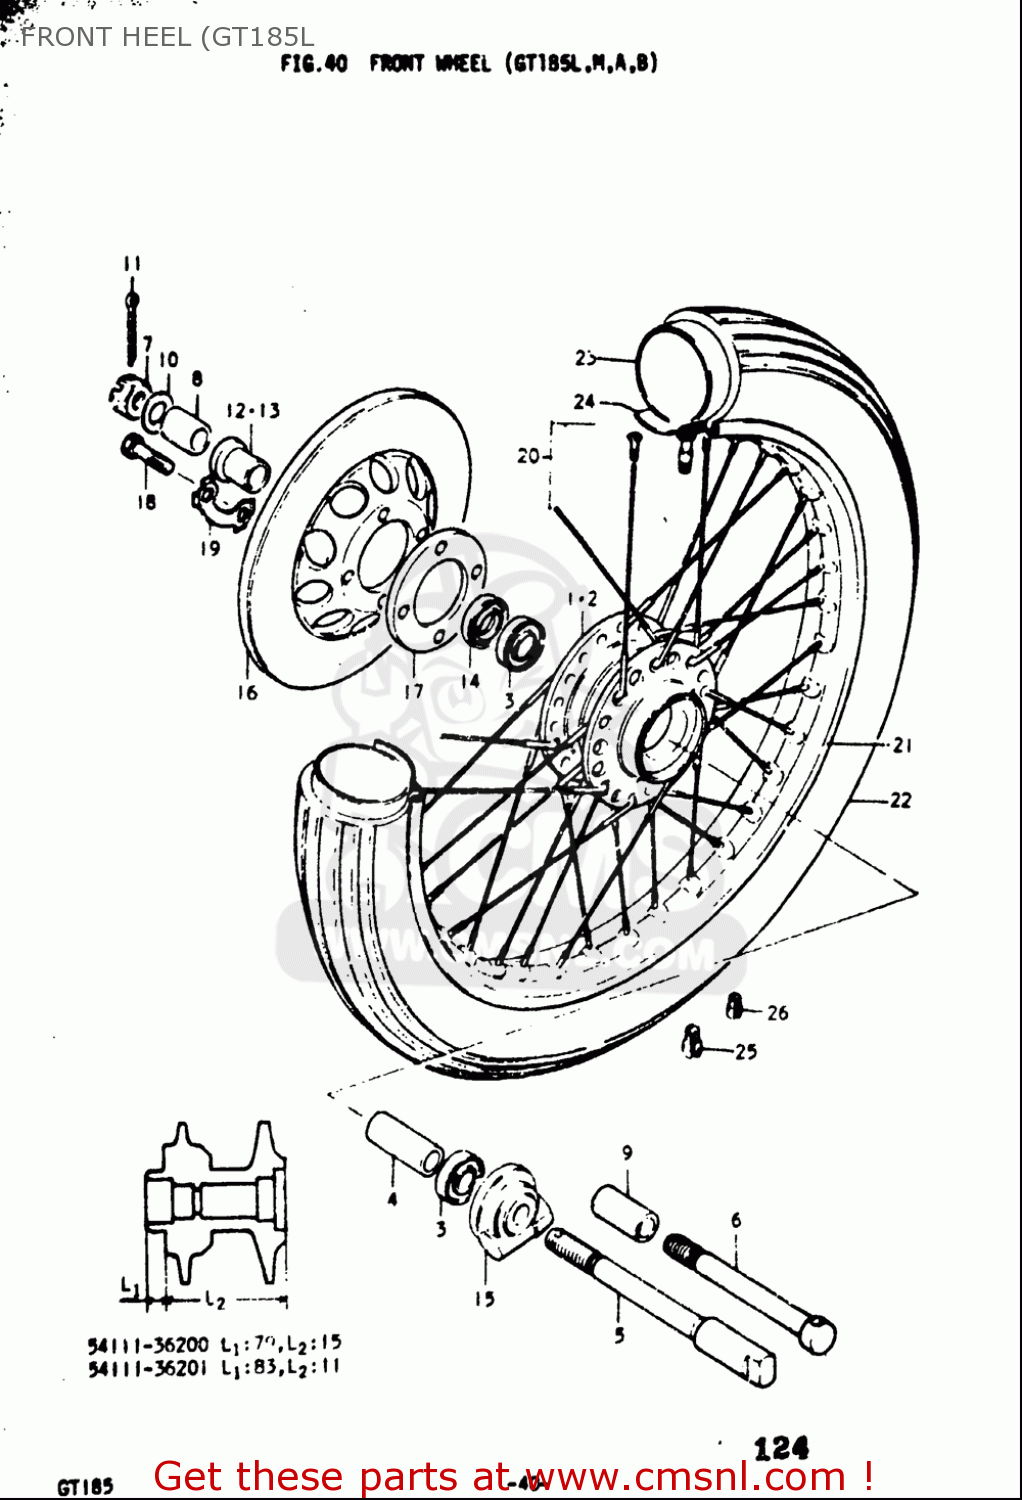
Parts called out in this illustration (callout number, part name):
1	HUB,FRONT
2	HUB,FRONT
3	BEARING
4	SPACER(12.5X19X52)
7	NUT 12MM
8	SPACER(12X20X34.5)
9	SPACER (12X20X41)
10	WASHER
11	PIN
12	SPACER,FRONT AXLE,RIGHT
13	SPACER,FRONT AXLE,RIGHT
14	SEAL,OIL(20X37X7)
18	BOLT(8X30)
20	SPOKE ASSY,FR
21	RIM,FR WHEEL
22	TIRE,FR(2.75-18)
23	TUBE ASSY,WHEEL INNER
24	PROTECTOR,INNER TUBE
25	BALANCER,WHEEL (B)
26	BALANCER,WHEEL (30G)
